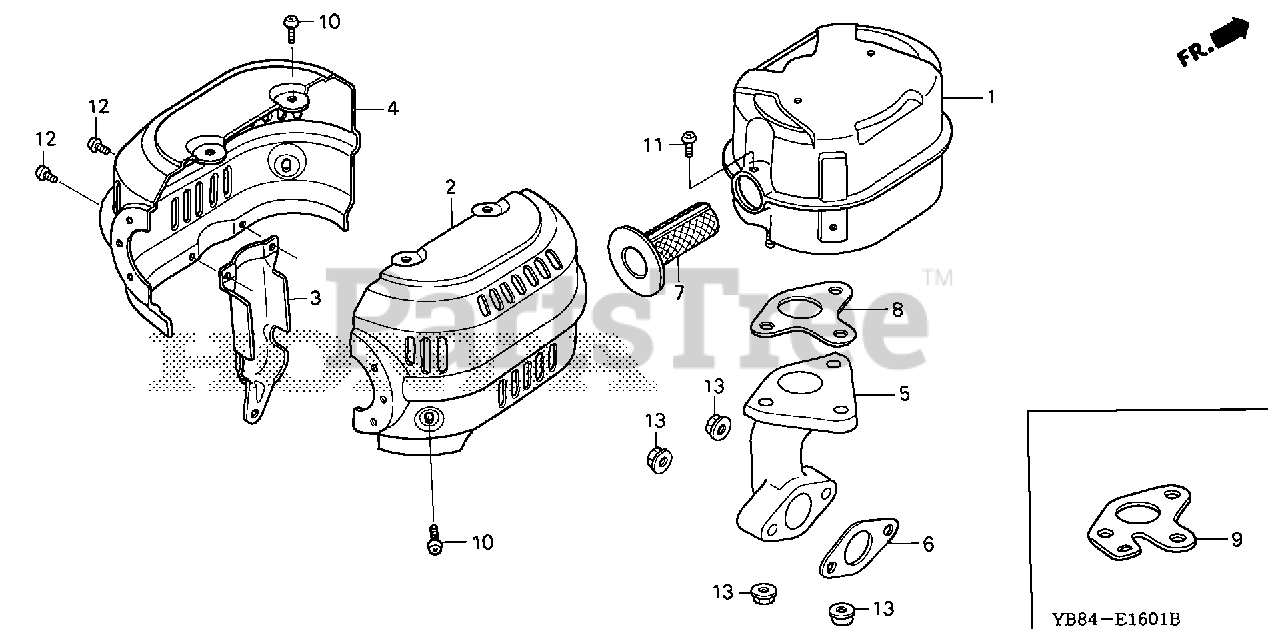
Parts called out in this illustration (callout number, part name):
1	MUFFLER
2	PROTECTOR, R. MUFFLER (ALUMINIZED)
4	PROTECTOR, L. MUFFLER (Honda Code 4049946). (ALUMINIZED)
5	PIPE, EX.
6	GASKET, EX. PIPE
7	ARRESTER, SPARK
8	GASKET, MUFFLER (NIPPON LEAKLESS)
9	GASKET, MUFFLER (ARRESTER)
10	SCREW, TAPPING (5X8)
11	SCREW, TAPPING (4X6) (TO INSTALL OPTIONAL SPARK ARRESTER)
13	NUT, FLANGE (8MM)
